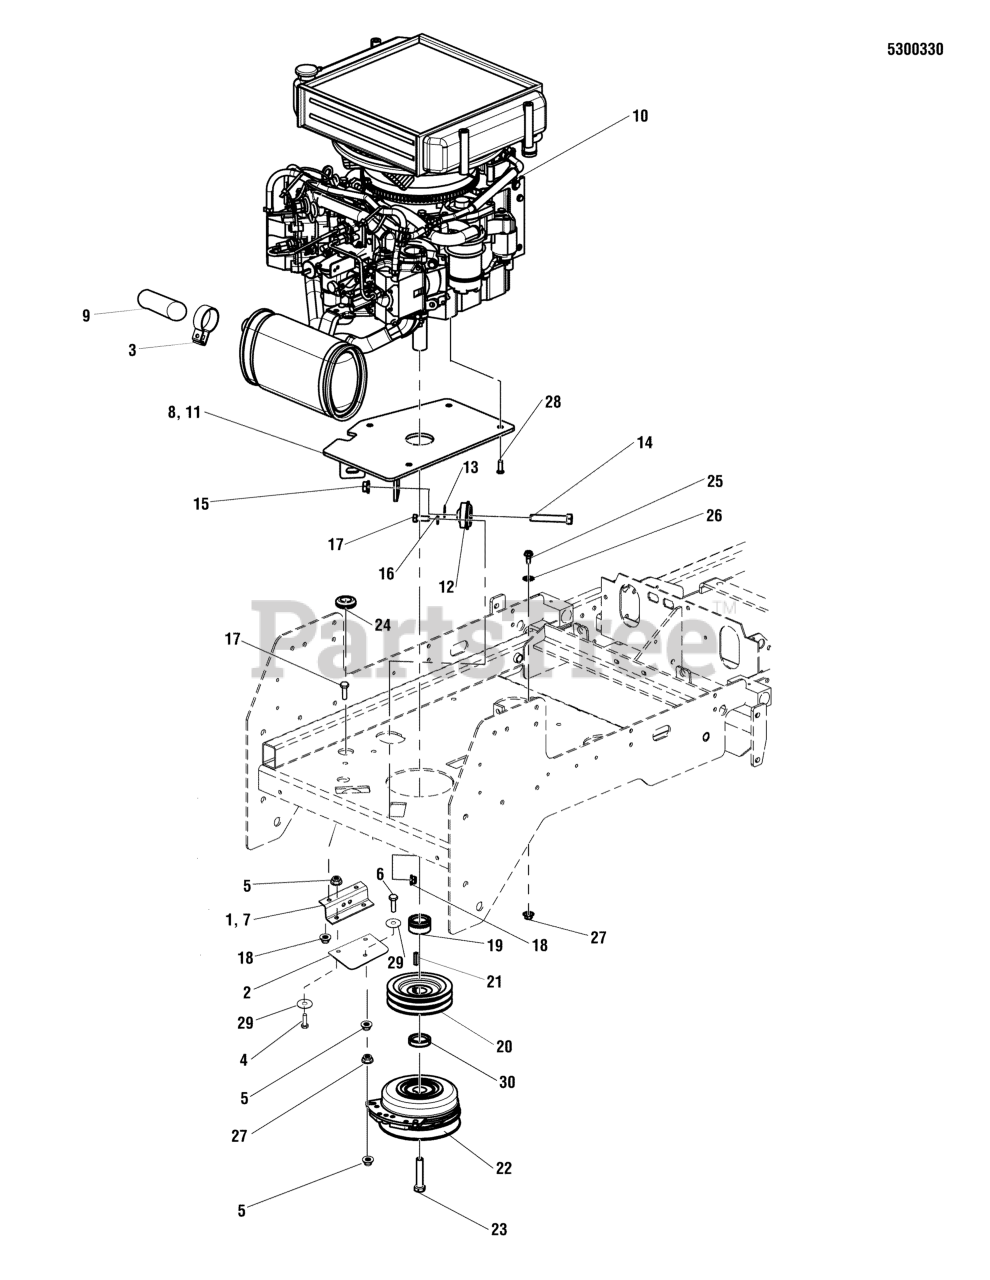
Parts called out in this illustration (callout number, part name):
1	ANCHOR, CLUTCH - BLK
2	CLUTCH ANCHOR PAD
3	CLAMP, TAIL PIPE
4	BOLT, 5/16-18 X 1" GD5 YZ
5	NUT, 5/16-18 HEX NYLOCK FLANGE
6	BOLT, 5/16-18 X 2-1/4 TFL, GD5 YZ
7	ANCHOR, CLUTCH - BLK
8	WELD, ENGINE MOUNT - YANMAR DIESEL - ORANGE MODEL
9	EXHAUST EXTENSION
10	ENGINE, DIESEL - YANMAR
11	WELD, ENGINE MOUNT - YANMAR DIESEL - RED MODEL
12	MOUNT, ISO, YANMAR DIESEL ENGINE
13	WASHER, 7/16" GD9 YZ
14	BOLT, 7/16-20 X 3" GD5
15	NUT, 7/16-20 HEX NYLON LOCK
16	WASHER, 3/8 SAE
17	BOLT, 3/8-16 X 1" GD5 CZ
18	NUT, 3/8-16 HEX NYLOCK FLANGE
19	SPACER, 1.13 X 1.75 X .97
20	PULLEY, 5.25 OD X 1.126 ID
21	KEY, 1/4 SQ X 1
22	* CLUTCH, 5218-134, WARNER
23	BOLT, CRANKSHAFT, MX10 X 80MM
24	GROMMET, 7/8
25	BOLT, 5/16-18 X 1", SELF-TAPPING
26	WASHER, 5/16, LOCK INT-EXT
27	NUT, 5/16-18 HEX SERRATED FLANGE (LARGE)
28	SCREW, M10 X 25MM - FHSCS
29	WASHER, .34 X 1.25 X 10 GA
30	SPACER, 1.13 X 1.75 X .62
